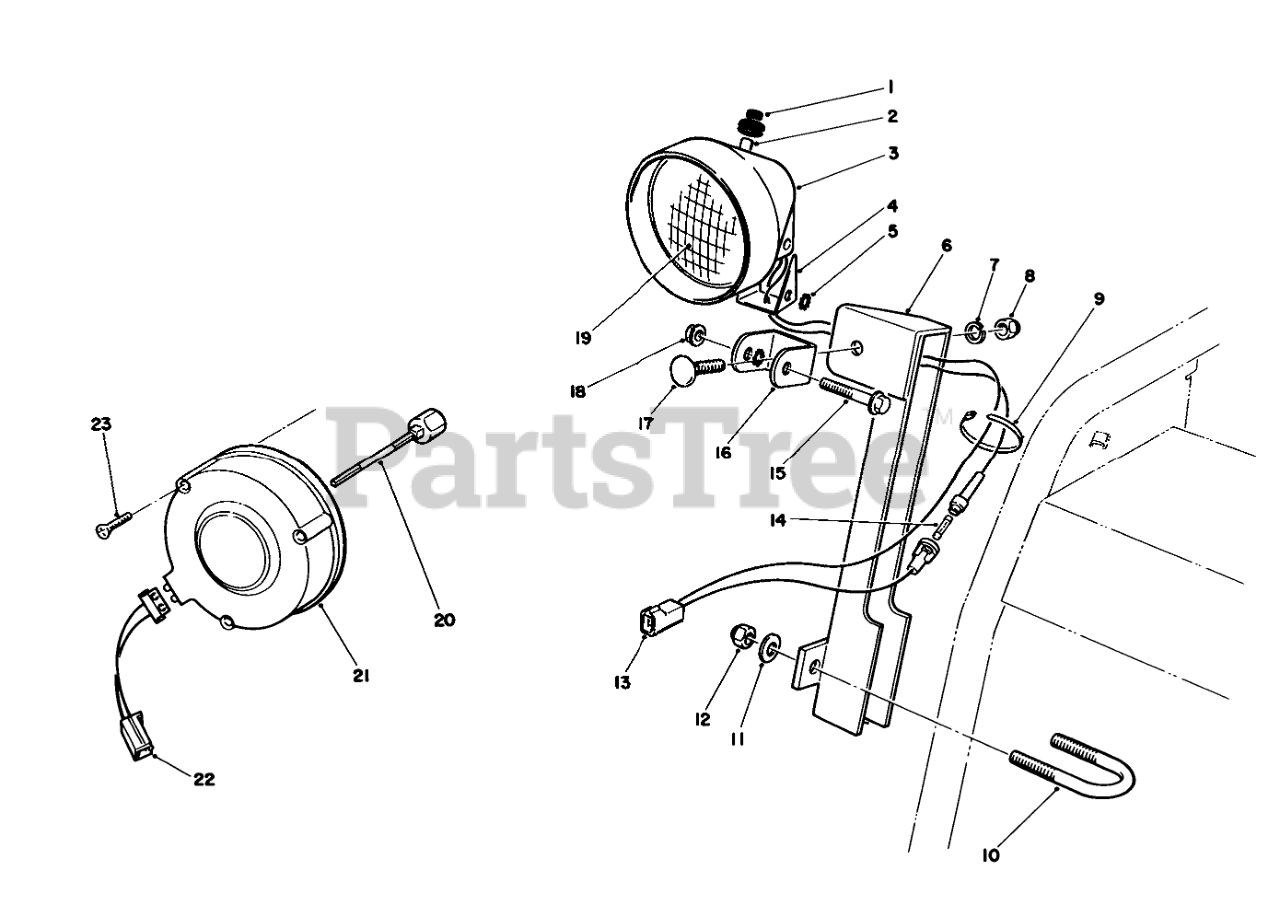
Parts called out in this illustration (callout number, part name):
1	BOOT-SWITCH
2	SWITCH ASM
3	Bucket-Headlamp
4	TO BE DISCONTINED-NOT NEEDED ON PRODUCT
5	WASHER-LOCK
6	Mount-Lamp
7	WASHER-LOCK
8	NUT-HEX
9	TIE-CABLE
10	U-BOLT
11	WASHER-PLAIN
12	NUT-LOCK, NI
13	WIRE ASM
14	Fuse-7-1/2 Amp.
15	SCREW-HH
16	BRACKET
17	BOLT-CARR
18	NUT-HF
19	BEAM-SEALED
20	Shaft-Alternator, 3 Inch
21	Alternator
22	Connector-Wire
23	SELF TAP SCREW
